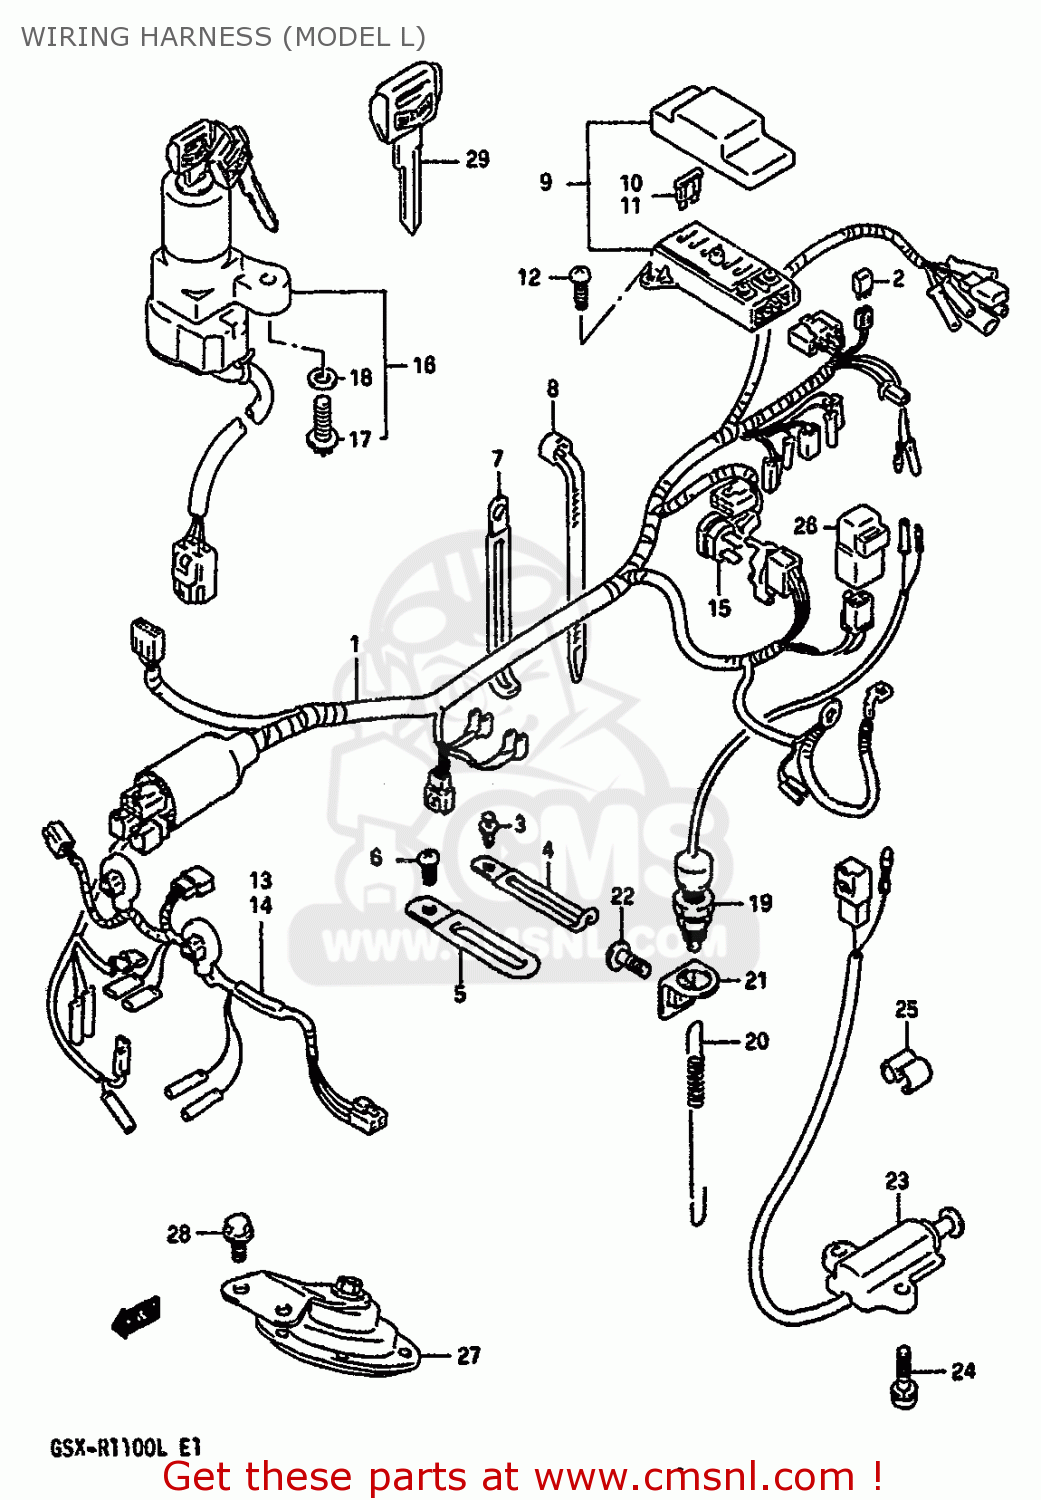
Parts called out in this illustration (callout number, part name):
1	HARNESS,WIRING
2	DIODE(STANLEY DE8804)
3	CLIP
4	CLAMP
5	CLAMP
6	SCREW
7	CLAMP
8	CLAMP(L:125)
9	BOX ASSY,FUSE
10	FUSE(10A)
11	FUSE(20A)
12	SCREW
13	WIRE,HEADLAMP LEAD
14	WIRE,HEADLAMP LEAD
15	BREAKER ASSY,CIRCUT
16	LOCK ASSEMBLY,STEERING
17	SCREW(6X18)
18	WASHER
19	SWITCH ASSY,STOP LAMP
20	SPRING
21	BRACKET,STOP LAMP SWITCH
22	SCREW(6X12)
23	SWITCH ASSEMBLY,SIDE STAND
24	SCREW
25	CLIP
27	HORN ASSY
28	BOLT
29	KEY,BLANK
30	BOLT
31	KEY,BLANK
